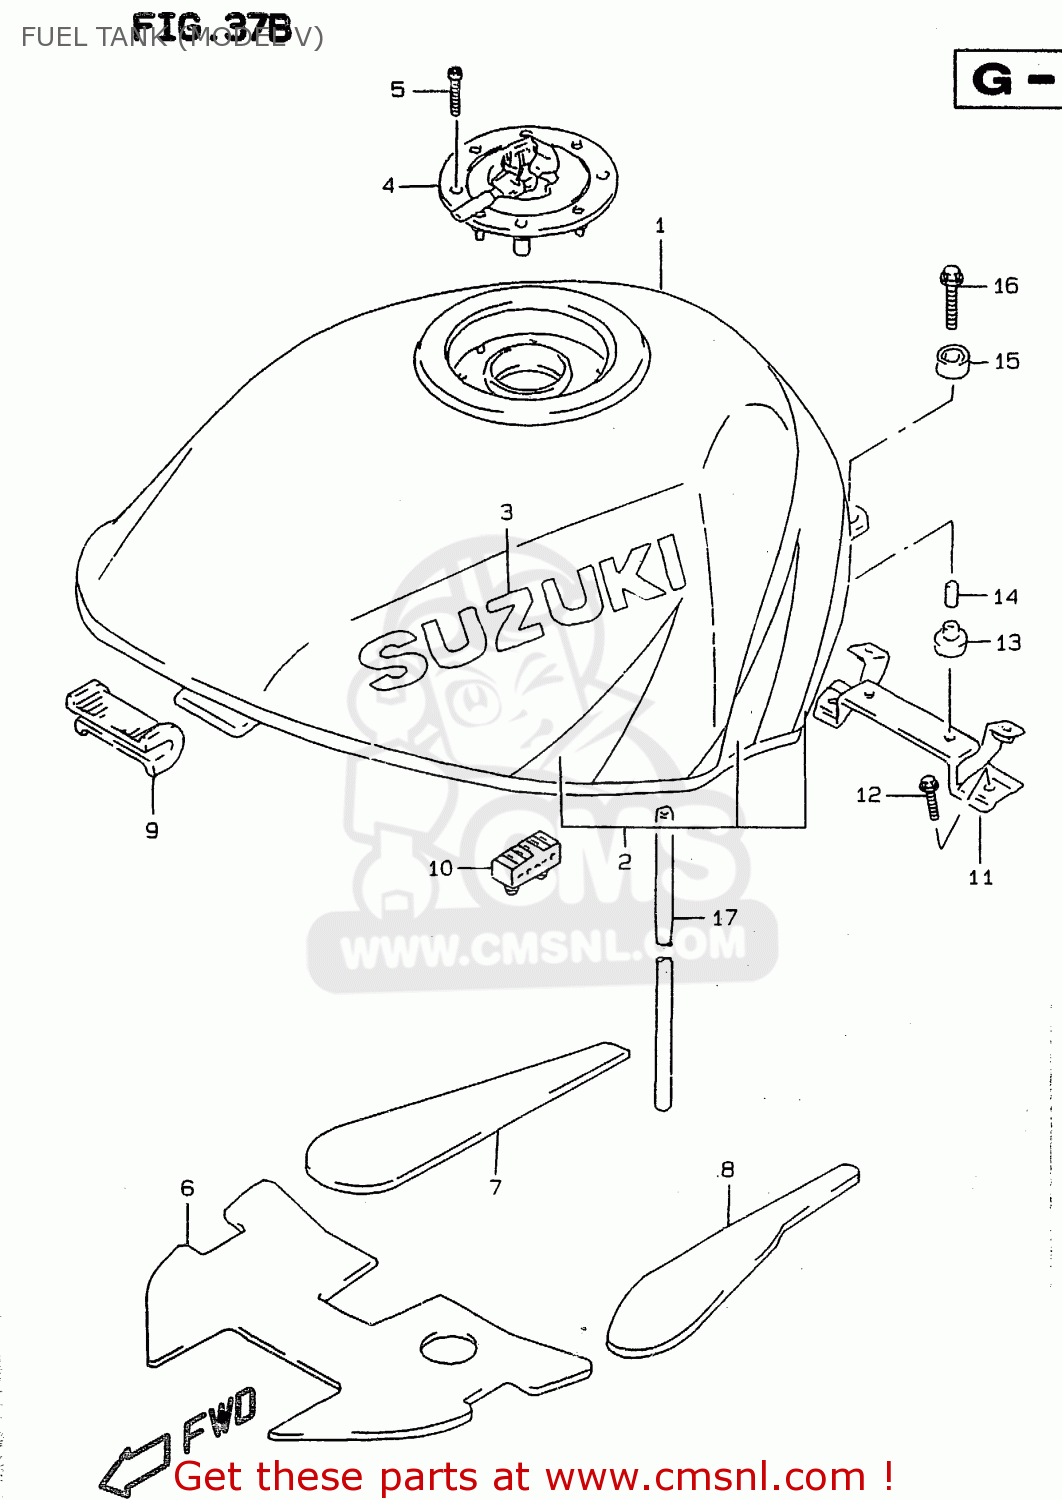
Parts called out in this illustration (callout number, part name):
1	TANK ASSEMBLY,FUEL
2	TAPE SET,FUEL TANK
3	EMBLEM,FUEL TANK
4	CAP SET,FUEL TANK
5	BOLT(5X20)
6	SHIELD,FUEL TANK HEAT NO.1
7	SHIELD,FUEL TANK HEAT NO.2
8	SHIELD,FUEL TANK HEAT NO.3
9	CUSHION,FUEL TANK FR
10	CUSHION,SEAT(40X20X15)
11	BRACKET,FUEL TANK RR
12	BOLT
13	CUSHION
14	SPACER(6.5X9X18)
15	CUSHION
16	BOLT
17	HOSE(7X10.2X600)
